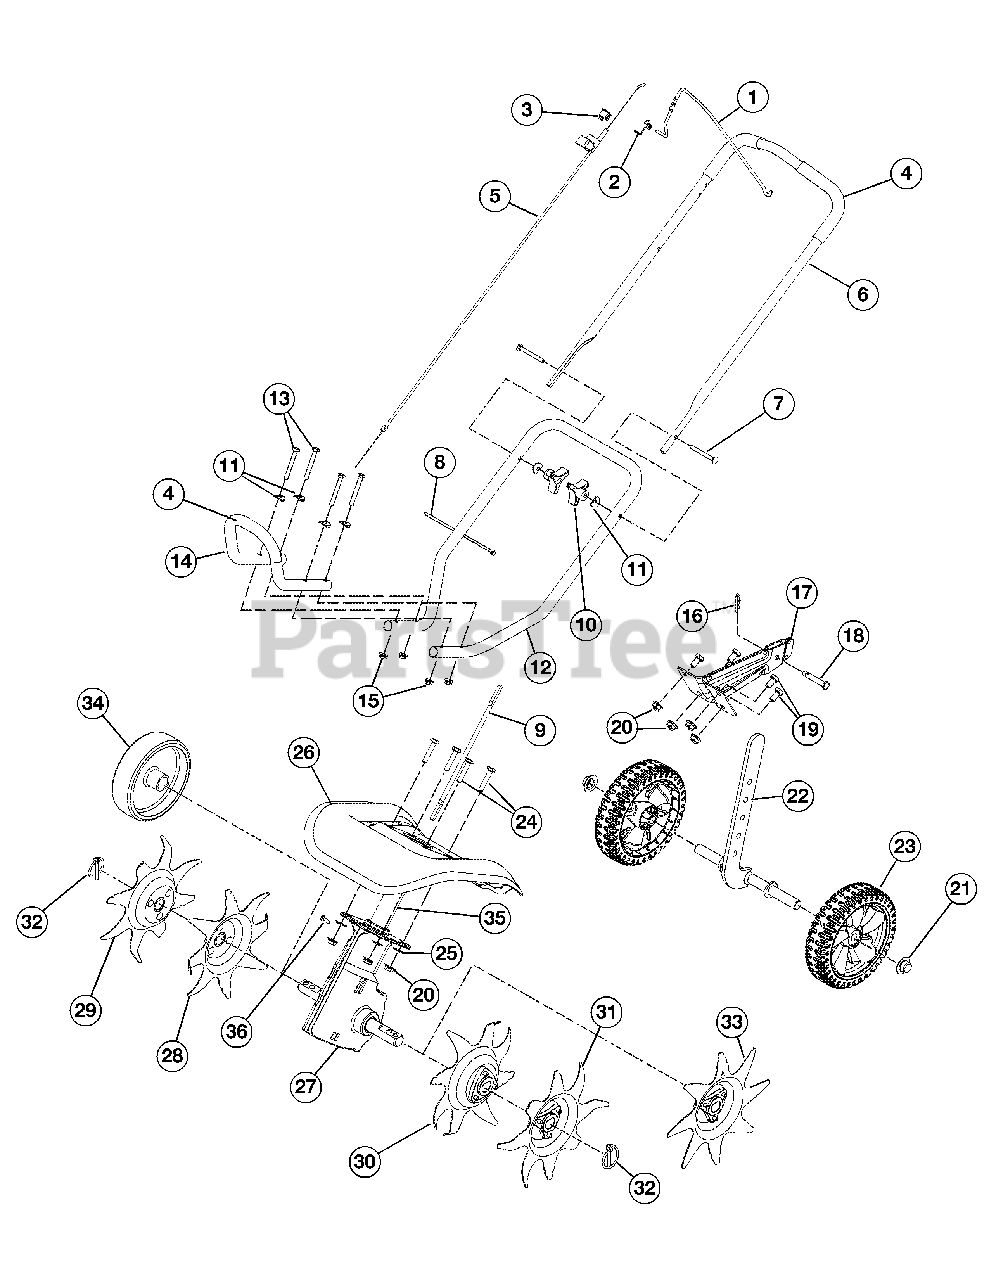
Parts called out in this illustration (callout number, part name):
1	Trottle Control
2	Torsion Spring
3	On/Off Switch
4	Foam Grip
5	Throttle Cable
6	Upper Handle
8	Cable Tie
9	Flex Shaft
11	Shoulder Washer
12	Lower Handle
13	Screw
14	Front Handle
15	Lock Nut
16	Cotter Pin
17	Tailpiece Bracket Assembly
18	Clevis Pin
19	Cap Screw
20	Lock Nut
21	Cap Push
22	Wheel Support Bracket Assembly
23	Wheel
24	Cap Screw
25	Washer
26	Tine Shield
27	Gear Box Assembly
28	Inner Tine (right side)
29	Outer Tine (right side)
30	Inner Tine (left side)
31	Outer Tine (left side)
33	Edger Tine
34	Edger Wheel
35	Drive Shaft Housing
36	Anti Rotation Screw
